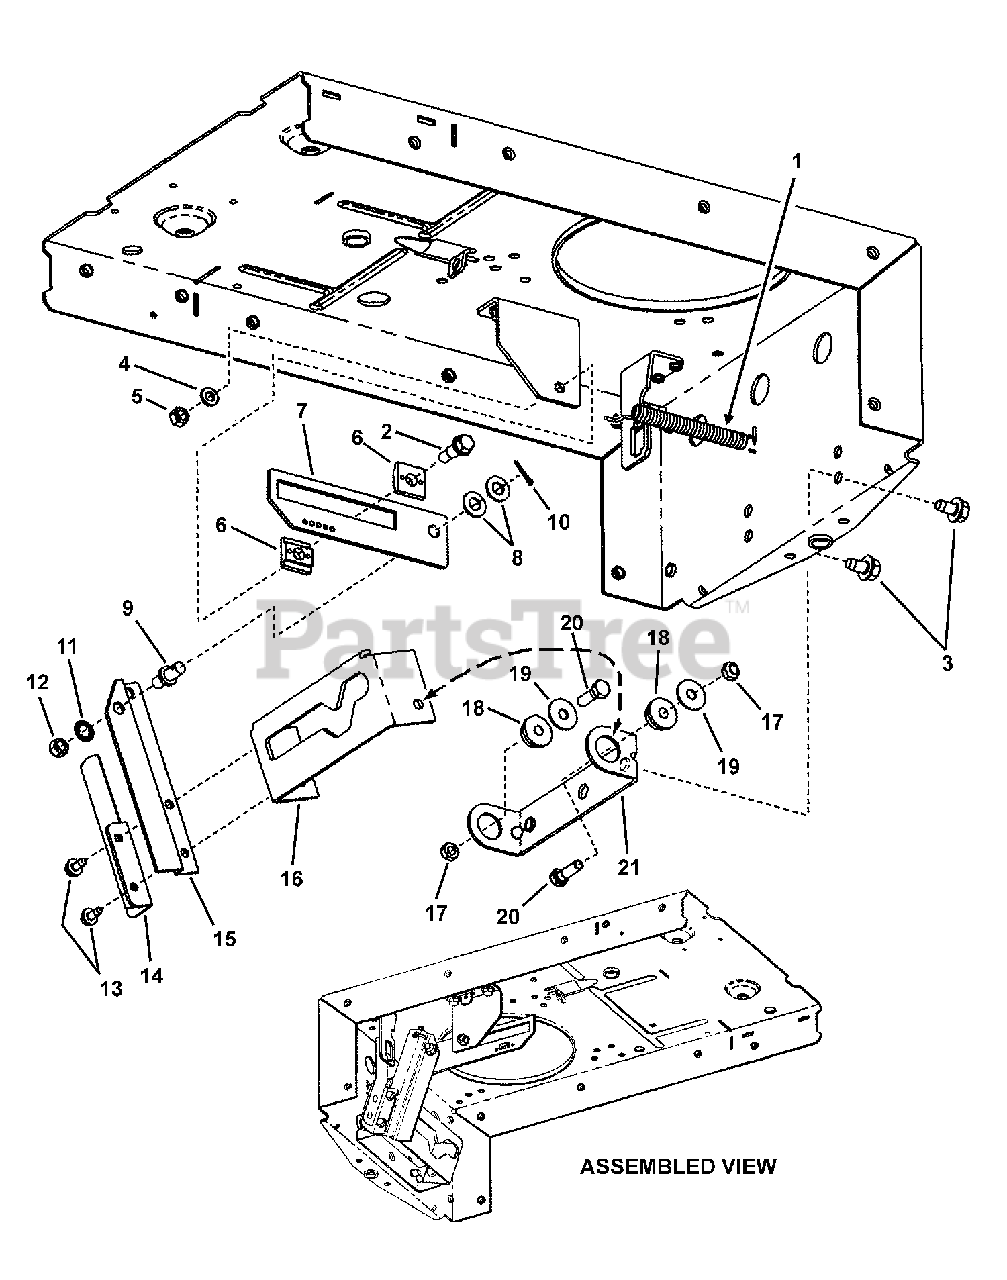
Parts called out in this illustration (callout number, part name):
1	SPRING, Clutch & Brake
2	BOLT, 5/16-18 Shoulder
3	SCREW, 3/8-16 x 5/8" Hex Washer Self-Tap
4	WASHER, 5/16" Split Lock
5	NUT, 5/16-18 Hex, GR 5 or B
6	SLIDE HALF
7	BRACKET, Slide
8	WASHER, 3/8" Flat
9	STUD, Clutch Link (3/8-24 thread)
10	PIN, 3/32 x 3/4" Cotter
11	WASHER, 3/8" Internal Tooth Lock
12	NUT, 3/8-24 Hex, GR 5 or B
13	SCREW, 1/4-20 x 1/2" Hex Washer Self-Tap
14	ASSEMBLY, Leaf Spring
15	ARM, Yoke
16	LIFT, Yoke
17	NUT, Wheel Bolt 5/16-24 Hex Center Lock
18	BEARING, Yoke
19	FENDER WASHER, 5/16"
20	SCREW, 5/16-24 x 1" Hex Head Cap, GR 5
21	COLLAR, Yoke
